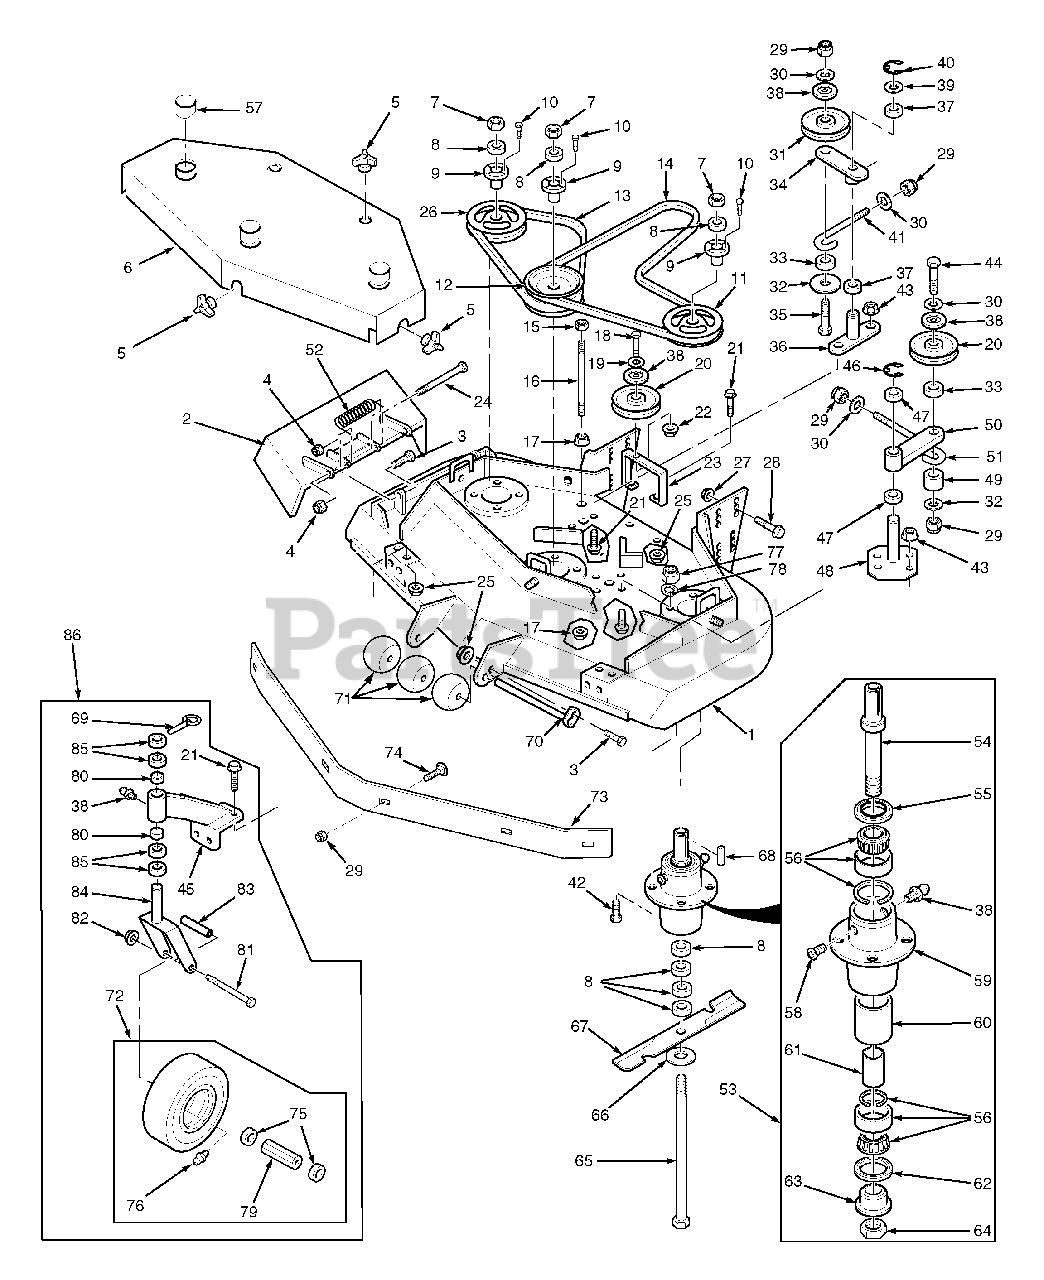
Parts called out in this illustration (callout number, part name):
1	Cutter Deck, Velocity +
2	Discharge Chute, Velocity Plus
3	Bolt, 5/16-18 x 1" Hex Head
4	Nut, 5/16-18 Elastic Stop
5	Wing Nut, 3/8-16
6	Belt Cover
7	Nut, 5/8-11 Hex Head
8	Spacer, Cutter Blade
9	Tapered Hub, 1.125 Bore
10	Bolt, 1/4-20 x 1" Hex Head Grade 8
11	Pulley, 6.35 O.D.
12	Pulley, Double Groove, 6.35/5.75 O.D.
13	Belt, R.H. Blade Drive
14	Belt, Deck Drive
15	Lock Nut,3/8-16 Hex Head
16	Stud, 3/8-16 x 6-3/4"
17	Nut, 3/8-16 Serr. Flange
18	Bolt, 3/8-16 x 2-1/4"
19	Flatwasher, 3/8 (.391 x .938 x .105)
20	Pulley, Idler
21	Capscrew, 5/16-18 x 3/4 Ser. Flg. HH
22	Nut, 3/8-16 Elastic Stop
23	Idler Pulley Support
24	Bolt, Hex Head 5/16-18 x 4-1/4"
25	Nut, 5/16-18 Ser. Flg. Hex Hd.
26	Pulley, 5.75
27	Nut, 1/2-13 Ser. Flg. Hex Hd.
28	Capscrew, 1/2-13 x 1-1/4 Ser. Flg.
29	Nut, 3/8-16 Elastic Stop
30	Flatwasher, 3/8 (.391 x .938 x .105)
31	Pulley
32	Flatwasher, 3/8 (.375 x 1.50 x .060)
33	Spacer
34	Idler Arm
35	Bolt, 3/8-16 x 2-1/4"
36	Idler Pivot
37	Bearing
38	Dust Shield
39	Flatwasher, 3/4 ( .776 x 1.25 x .059)
39	Flatwasher, 3/4 ( .776 x 1.25 x .035)
40	Retaining Ring, .75 EXT 'E'
41	J-Rod Idler Pulley
42	Bolt, 5/16-18 x 1-1/2" Hex Head Gr 8
43	Nut, 5/16-18 Ser. Flange
44	Bolt, 3/8-16 x 3-1/2" Hex Head
45	Support Assembly
46	Retaining Ring, 1-1/8 EXT 'E'
47	Bearing
48	Idler Pivot Support
49	Spacer
50	Idler Arm
51	J-Rod, Drive Idler
52	Spring, Chute Return
53	Spindle Assembly
54	Shaft, Cutter Spindle
55	Seal, 2.00 O.D. x 1.50 Bore
56	Bearing Assembly
57	Shield, Spindle
58	Relief Fitting, Cutter Spindle
59	Spindle Housing
60	Spacer, Outside
61	Spacer, Inside
62	Seal, 2.00 O.D. x 1-5/8 Bore
63	Spindle Bushing Bottom
64	Nut, 1-1/16-18 UNEF-2B
65	Bolt, 5/8-11 x 9-1/2"
66	Flatwasher, 5/8 (.688 x 1.75 x .134)
67	Cutter Blade, 21" Standard
68	Key, 1/4 x 1/4 x 2"
69	Quick Pin
70	Shaft, Roller
71	Guide, Roller
72	Wheel Assy., Caster
73	Baffle, Custom-Cut 61V
74	Bolt, Carriage 3/8-16 x 1"
75	Retainer, Caster Wheel
76	Grease Fitting, 45 Deg. 1/4-28
77	Nut, Elastic Stop 5/16-18 Grade 8
78	Lock Washer, 5/16"
79	Roller Bearing, Caster Wheel
80	Bushing, 7/8 x 1" Flanged
81	Bolt, 1/2-13 x 5-1/2" Hex Head
82	Nut, 1/2-13 Elastic Stop
83	Sleeve, Caster Wheel Bearing
84	Caster Yoke
85	Spacer, Caster Yoke 1/2"
86	Caster Wheel and Support Assy.
